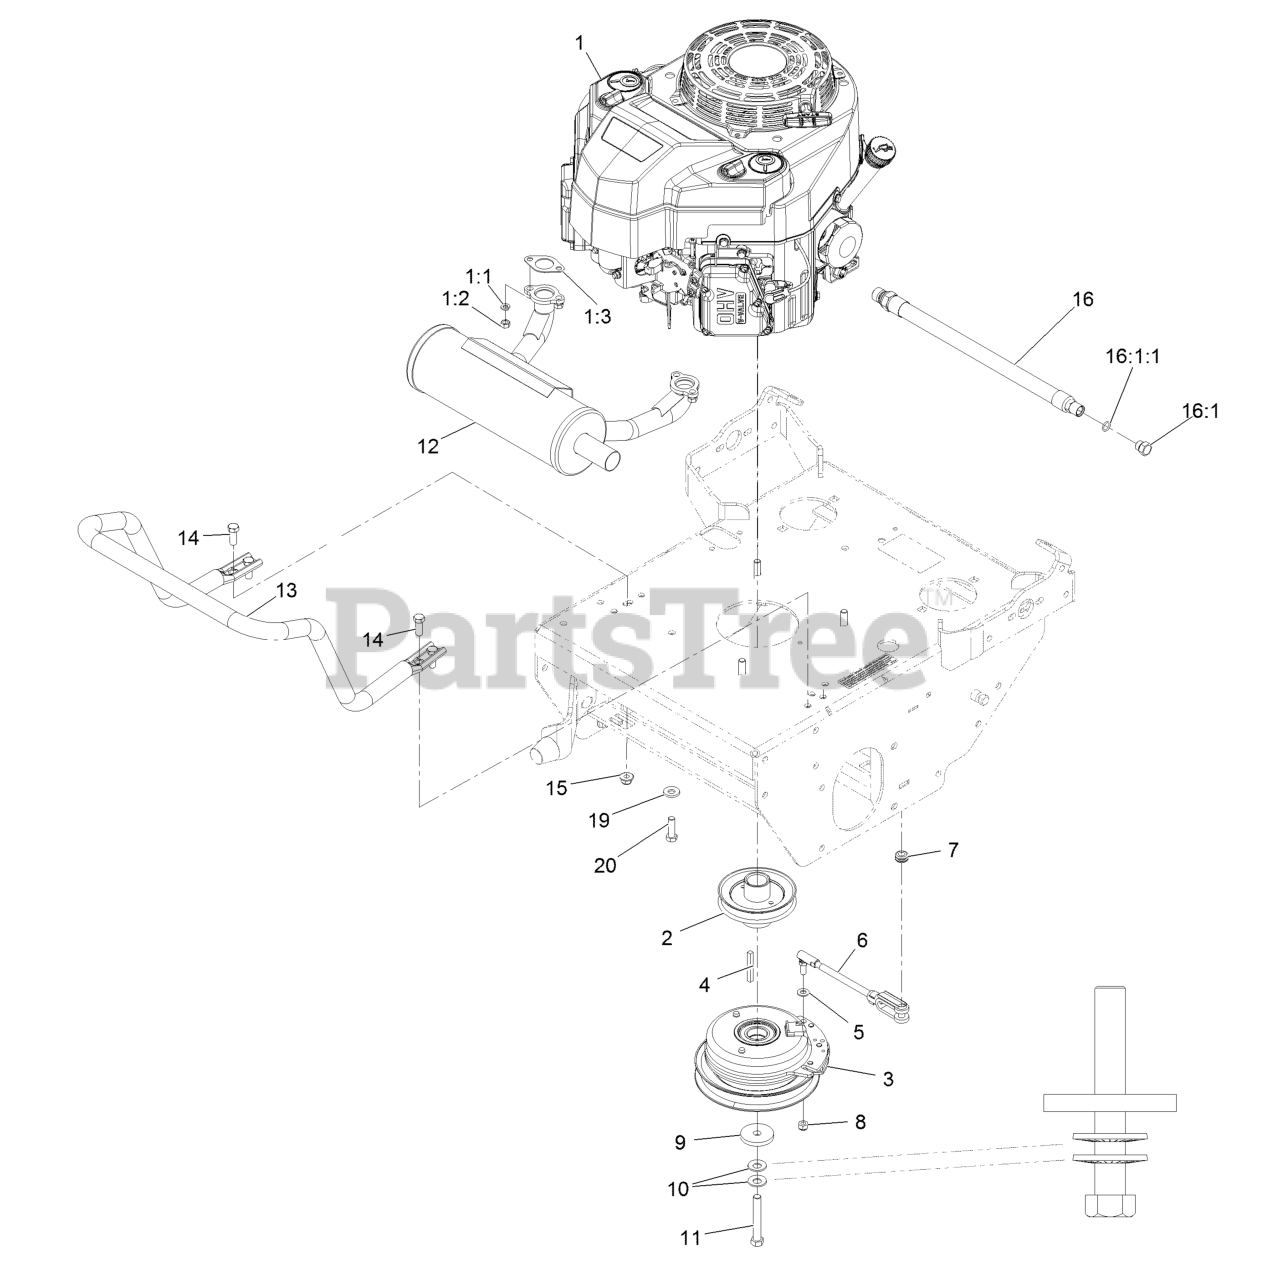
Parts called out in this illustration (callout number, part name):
1:1	Washer-Spring Lock M8
1:3	Gasket-Exhaust
2	Sheave, W/ Hub
3	Clutch, 105 Ft/Lbs, 1.13
4	Key-Machine 1/4 X 1/4 X 2
5	Washer-5/16 SAE
6	ASM, Clutch Anchor
7	Grommet
8	Nut-Lock 5/16-24
9	Washer-Clutch
10	Washer-Spring Disc 7/16
11	Screw-HH 7/16-20 X 3
12	Muffler-Horizontal
13	Guard-Muffler
14	Screw-HH 3/8-16 X 1
15	Nut-Nyloc 3/8-16 Flg
16	Asm-Oil Drain Hose W/Plug
16:1	Plug-W/O-Ring
16:1:1	O-Ring
19	Washer-Spring Disc 3/8
20	Screw-HH 3/8-16 X 1 1/4
